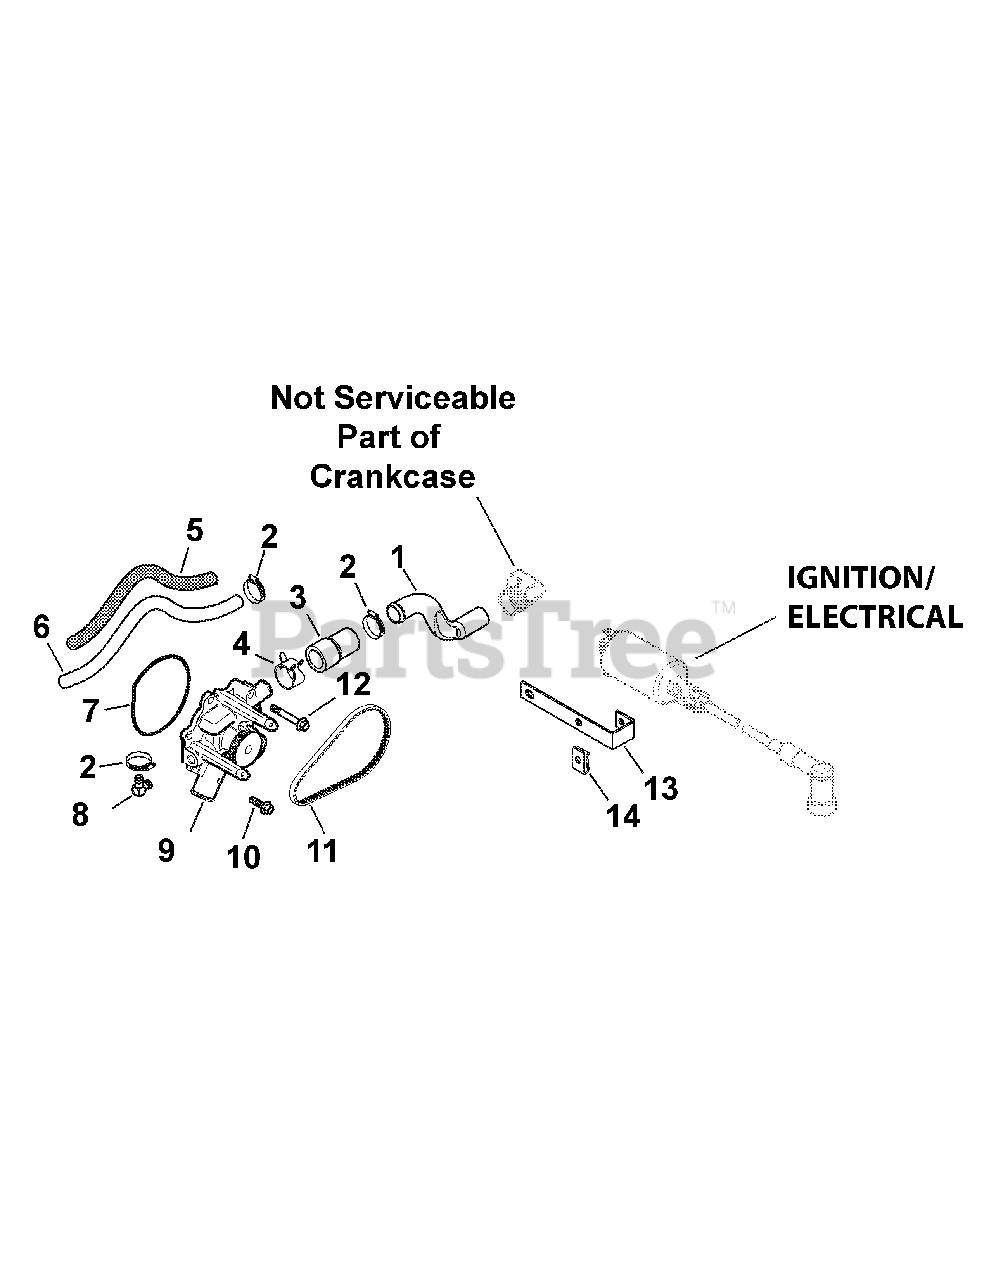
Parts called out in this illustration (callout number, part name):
1	Tube, Crossover
2	Clamp, Hose
3	Tube, Crossover
5	Sleeve, Insulating 14"
6	Hose, By-pass
9	Pump, Water
10	Screw, Flg, M6 x 1.0 x 20
11	Belt, Water Pump
12	Screw, Flg, M6 x 1.0 x 40
13	Bracket, Ignition Coil (EFI)
